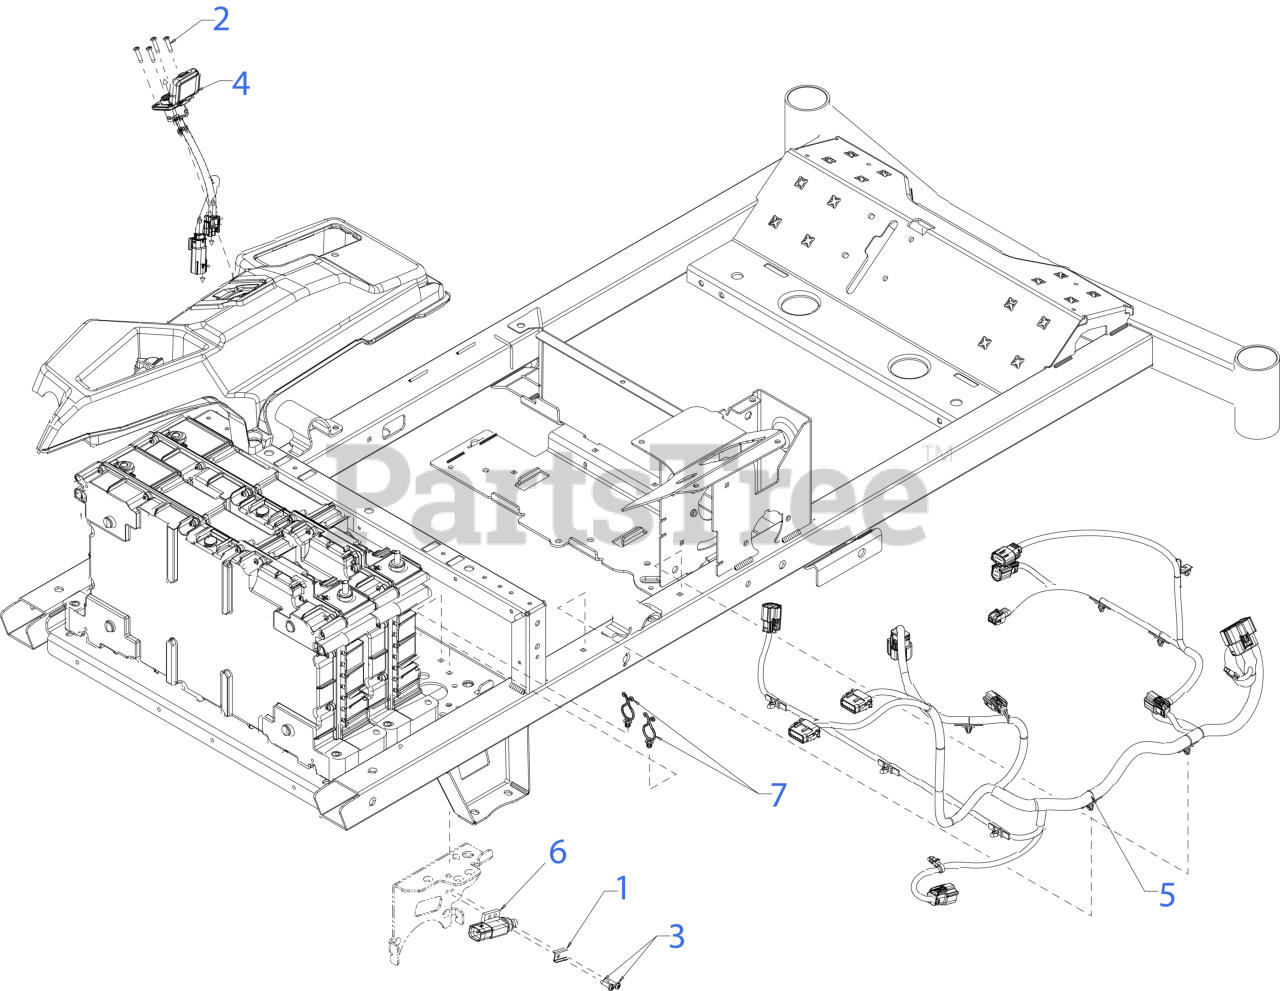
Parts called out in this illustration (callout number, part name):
1	PLATE-SWITCH
2	SCREW, #8-16X.750 PH
3	SCREW #10-24X11/16 T-25
4	CHARGER PORT HARNESS (8-PIN)
5	MAIN HARNESS
6	SEALED PLUNGER SWITCH
7	TWIST LOCK CLIP
